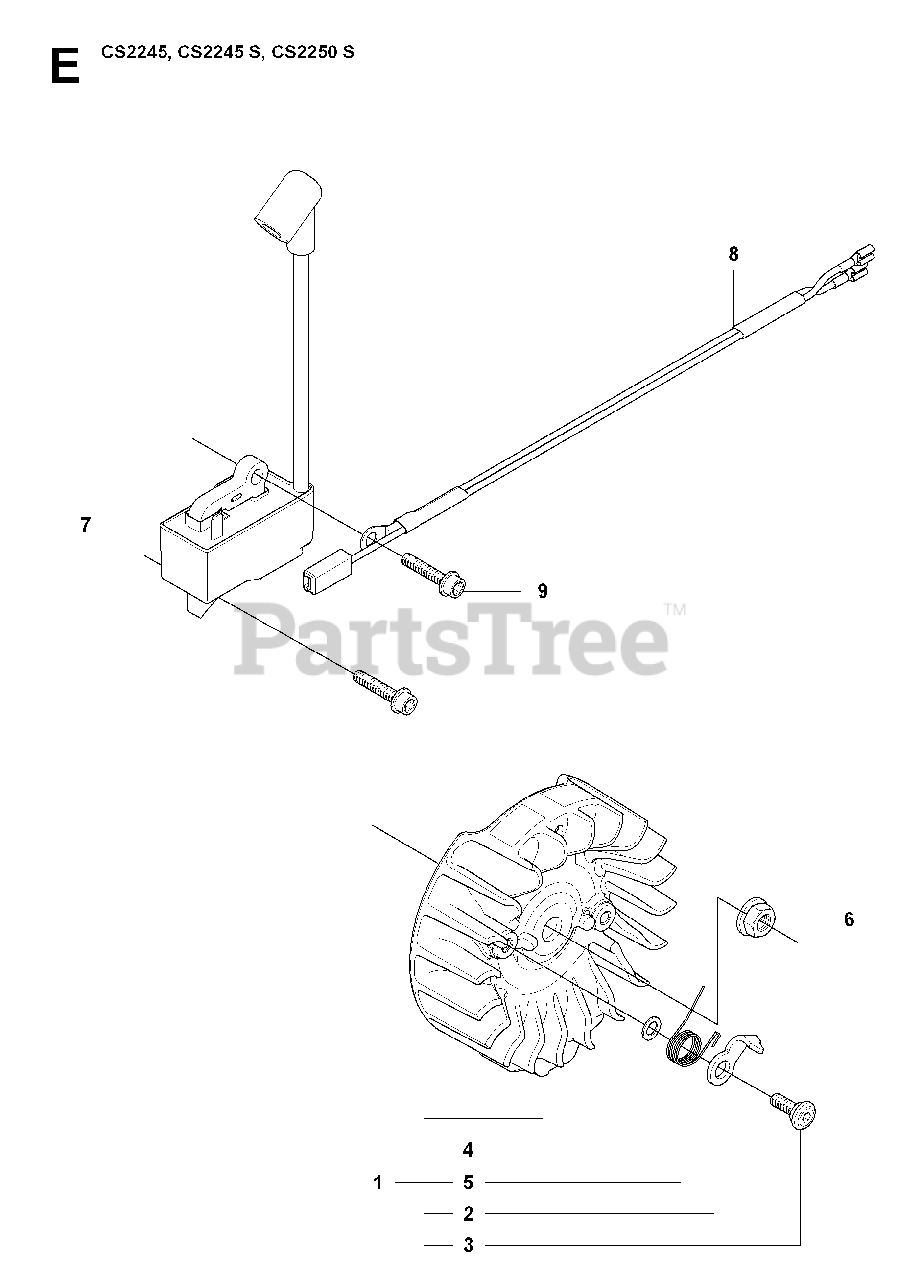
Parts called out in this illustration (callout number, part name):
1	FLYWHEEL ASSY
3	PIN, STARTER CATCH
5	%SPRING, STARTER CATCH
6	NUT W/ WASHER
7	%IGNITION MODULE
8	%WIRING ASSY
